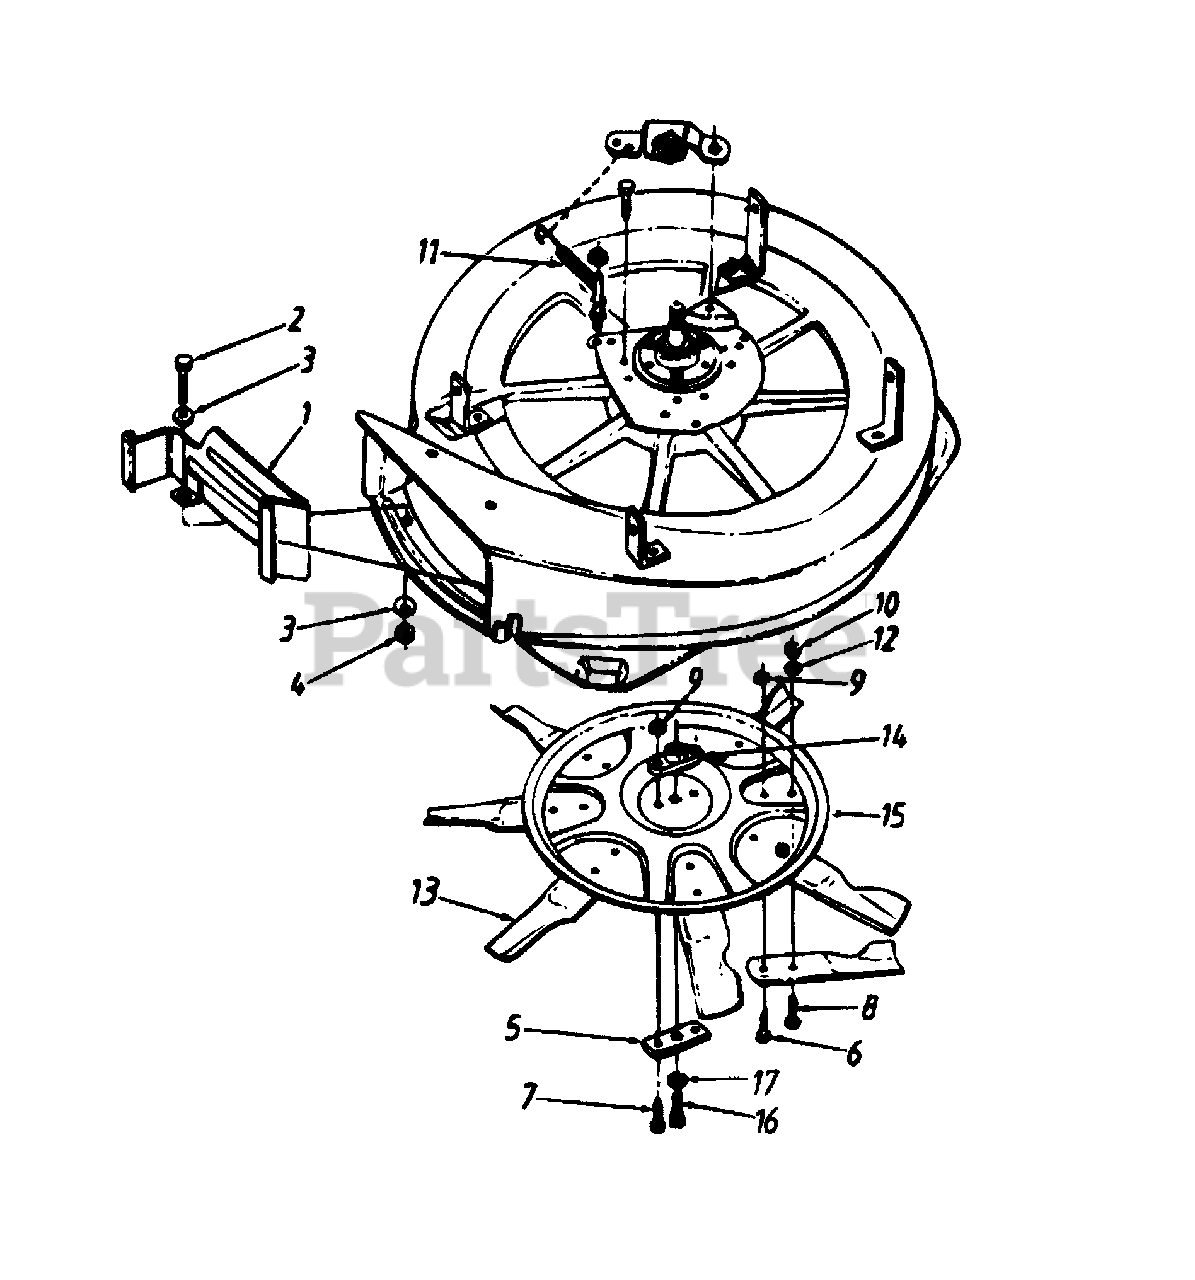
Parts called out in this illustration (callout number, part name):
1	Mulching Baffle Ass'y.
2	Hex Bolt 5/16-18 x .5"
3	Bell-Wash. .325" I.D.
4	Hex L-Nut 5/16-18 Thd.
7	Hex Bolt 5/16-24 x 1.25" Lg. (Gr. 5)
8	Hex Bolt 3/8-24 x .88" Lg.
9	Hex L-Nut 5/16-24 Thd.
10	Hex L-Nut 3/8-24 Thd. (Gr. 5)
11	Extension Spring 3.2" Lg.
12	Fl-Wash. .406" I.D. x .75"
13	30" Mulching Blade Tip
14	Blade Adapter
15	30" Mulching Blade Disc
16	Hex Bolt 3/8-24 x 1.25" Lg.
17	L-Wash. 3/8" I.D.
